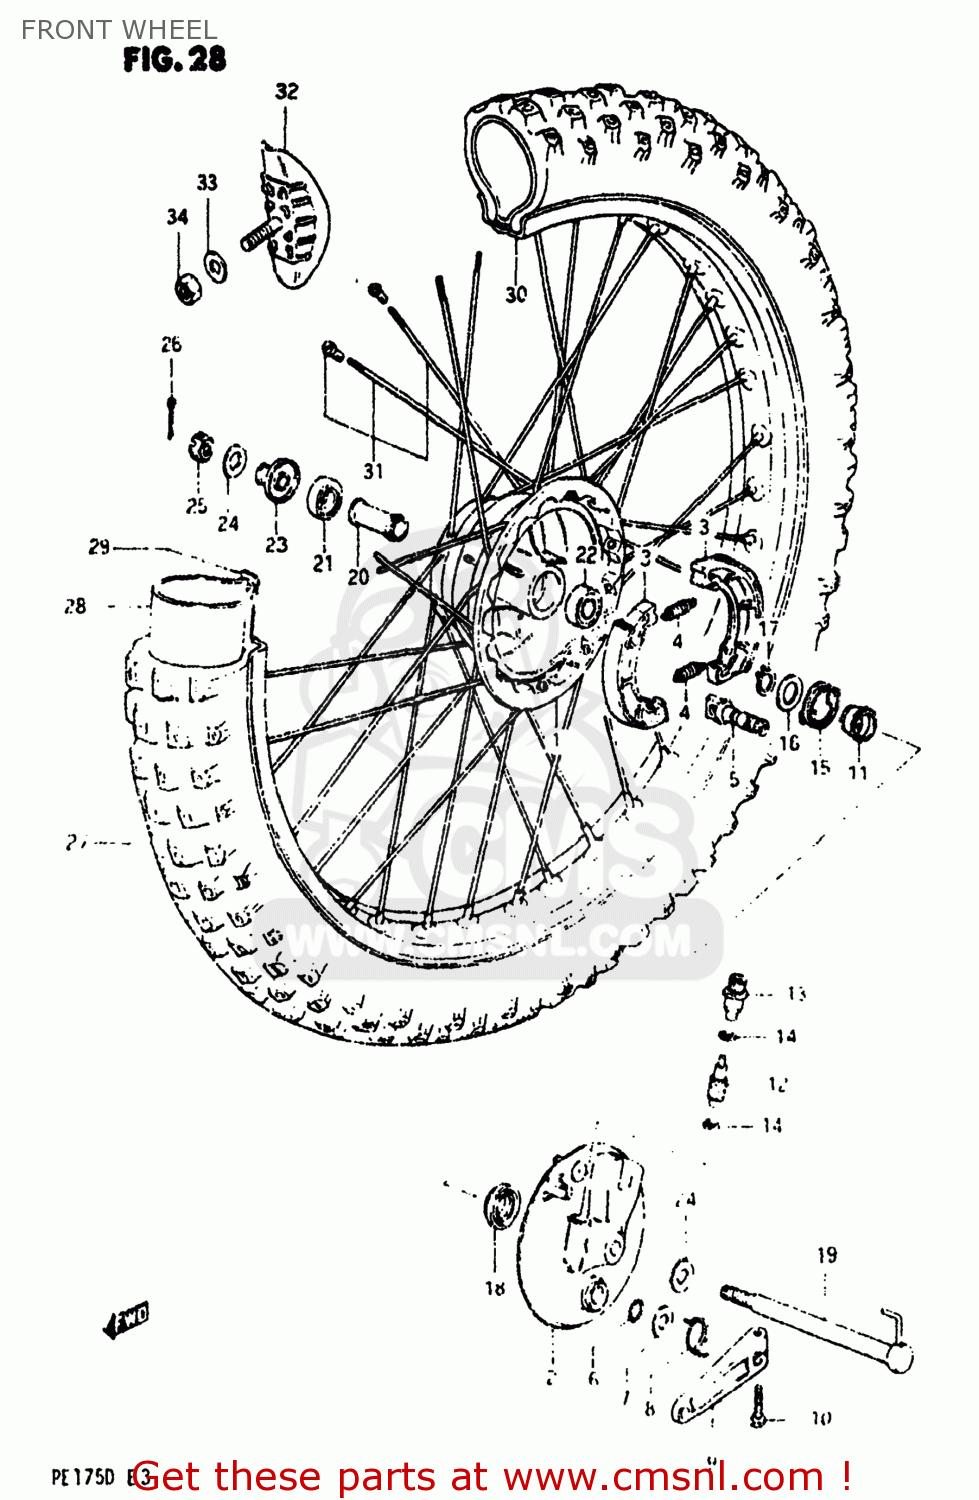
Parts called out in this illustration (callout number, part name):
1	HUB,FRONT
2	PANEL,FRONT HUB
3	SHOE,BRAKE (ASB)
4	SPRING
5	CAM,FR BRAKE
6	O RING(D:2.5,ID:11.4)
7	WASHER(12.5X20X1)
8	SPRING
9	LEVER,FRONT BRAKE CAM
10	BOLT
11	GEAR,SPEEDOMETER
12	PINION,SPEEDOMETER
13	BUSH,SPEEDOMETER PINION OUTER
14	WASHER (5.1X9X0.4)
15	DRIVER,SPEEDOMETER GEAR
16	WASHER(22.5X27X1)
17	CIRCLIP
18	SEAL,OIL(26X38X4)
19	AXLE,FRONT
20	SPACER,FRONT HUB BEARING
21	BEARING
22	BEARING
23	SPACER,FRONT AXLE,RIGHT
24	WASHER
25	NUT, REAR AXLE
26	COTTER PIN
27	TIRE,FRONT
28	TUBE
29	PROTECTOR,WHEEL,INNER
30	RIM,FRONT WHEEL
31	SPOKE SET,FRONT
32	STOPPER,BEAD
33	WASHER
34	NUT 8MM
